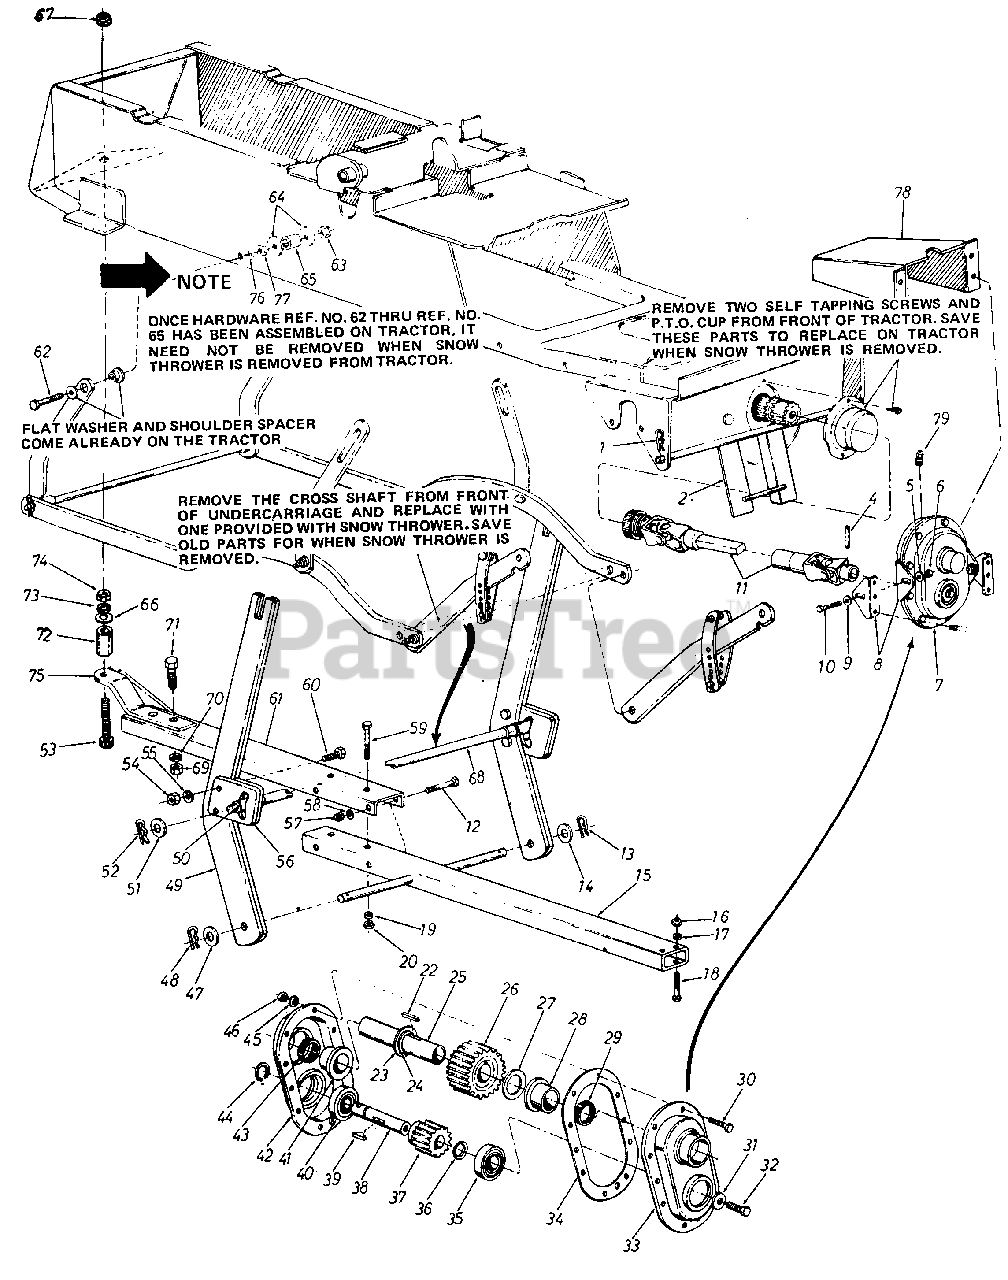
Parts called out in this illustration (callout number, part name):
1	Intern. Cotter Pin 3/4" Dia.
2	Guide Bracket Ass'y.
4	Spring Pin Spirol 1 /4 " Dia. x Lg.
5	Be lleville Wash. .341 " I.D. x.88" O.D.
6	Hex Nut 5/16-18 Thd.*
7	Gear Box Ass'y. Comp.
8	Gear Box Support Brkt.
9	Belleville Wash. .341 " I.D. x .88" O.D.
10	Hex Scr-5/16-18 x .75" Lg.
11	Universal Drive Shaft Ass'y.
12	Hex Scr. 3/8-24 x 4.50" Lg.*
13	Hair Pin Cotter
14	Fl.-Wash. .62" I.D. x 1.12" O.D.
15	L i ft Shaft Ass'y.
16	Hex Ins. Jam L.-Nut 3/8-24 Thd.
17	L.-Wash. 3/8" Scr.*
18	Hex Scr. 3/8-24 x 2.75" Lg.*
19	L.-Wash. 3/8" Scr.*
20	Hex Ins. Jam L.-Nut 3/8-24 Thd.
22	Hi-Pro Key 1/4" x 7/8" Dia.
23	Fl.-Wash 1.31 " I.D. x 2.00" O.D. x .060
24	Snap Ring for 1.25" Dia. Shaft
25	Gear Shaft 1.25" Dia. x 6.0" Lg.
26	28 Teeth Spur Gear
27	Fl.-Wash. 1.31" I.D. x 2.00 O.D. x .060
28	Flange Bearing 1.25" I.D. x 1.75" O.D.
29	Oil Seal 1.25" I.D. x 1.75" O.D. x .26
30	Hex Scr. 1/4-28 x .88" Lg.
31	Fl.-Wash. .40 I.D. x 1.25" O.D. x . 1 60
32	Hex L.-Scr. 3/8-24 x 1.00" Lg.
33	Complete Gear Housing Half-L.H.
34	Gasket
35	Ball Bearing 1.00" I.D. x 2.00" O.D.
36	Fl.-Wash. 1.03" I.D. x 1.63" x . 090
37	15 Teeth Spur Gear
38	Input Shaft
39	Woodruff Key 1/4" x 3/4" Dia.
40	Ball Bearing 1.00" I.D. x 2.00" O.D.
41	Flange Bearing 1.25" I.D. x 1.75" O.D.
42	Complete Gear Housing Half-R.H.
43	Oil Seal 1.25" I.D. x 1.75 " O.D. x .26
44	Snap Ring for 1.00" Dia. Shaft
45	Spring Wash. 1/4" I.D.
46	Hex Nut 1/4-28 Thd.
47	Fl. Wash. .62" I.D. x 1.12" O.D.
48	Hair Pin Cotter
51	Fl. Wash. .62" I.D. x 1.12" O.D.
52	Hair Pin Cotter
53	Hex Bolt 5/8-18 x 4.00" Lg.
54	Hex Nut 5/16-18 Thd.*
55	L. Wash. 5/16" Scr.
58	L. Wash. 3/8" Scr.*
59	Hex Scr. 3/8-24 x 2.75"
60	Hex Scr. 5/16-18 x 1.00" Lg.*
61	Lift Bracket
62	Hex Scr. 3/8-24 x 2.50"
63	Hex Jam L.-Nut 3/8-24 Thd.
64	Fl.-Wash...375 I.D. x 1.00" O.D x .135"
65	Spacer .275 I.D. x .625 O.D. x 440
66	Fl.-Wash. .66" I.D. x 1.25" O.D. x .100
67	Hex Jam L.-Nut 5/8-18 Thd.
68	Cross Shaft Ass'y.
69	Hex Nut 1/2-13 Thd.*
70	L.-Wash. 1/2" Scr.*
71	Hex Scr. 1/2-13 x 1.25"
72	Bushing
73	L.-Wash. 5/8" Scr.*
74	Hex Jam Nut 5/8-18 Thd.
75	Tongue Ass'y.
76	L.-Wash. 3/8" I.D.*
77	Hex Nut 3/8-24Thd.*
78	Drive Shaft Cover
79	Grease Fitting
